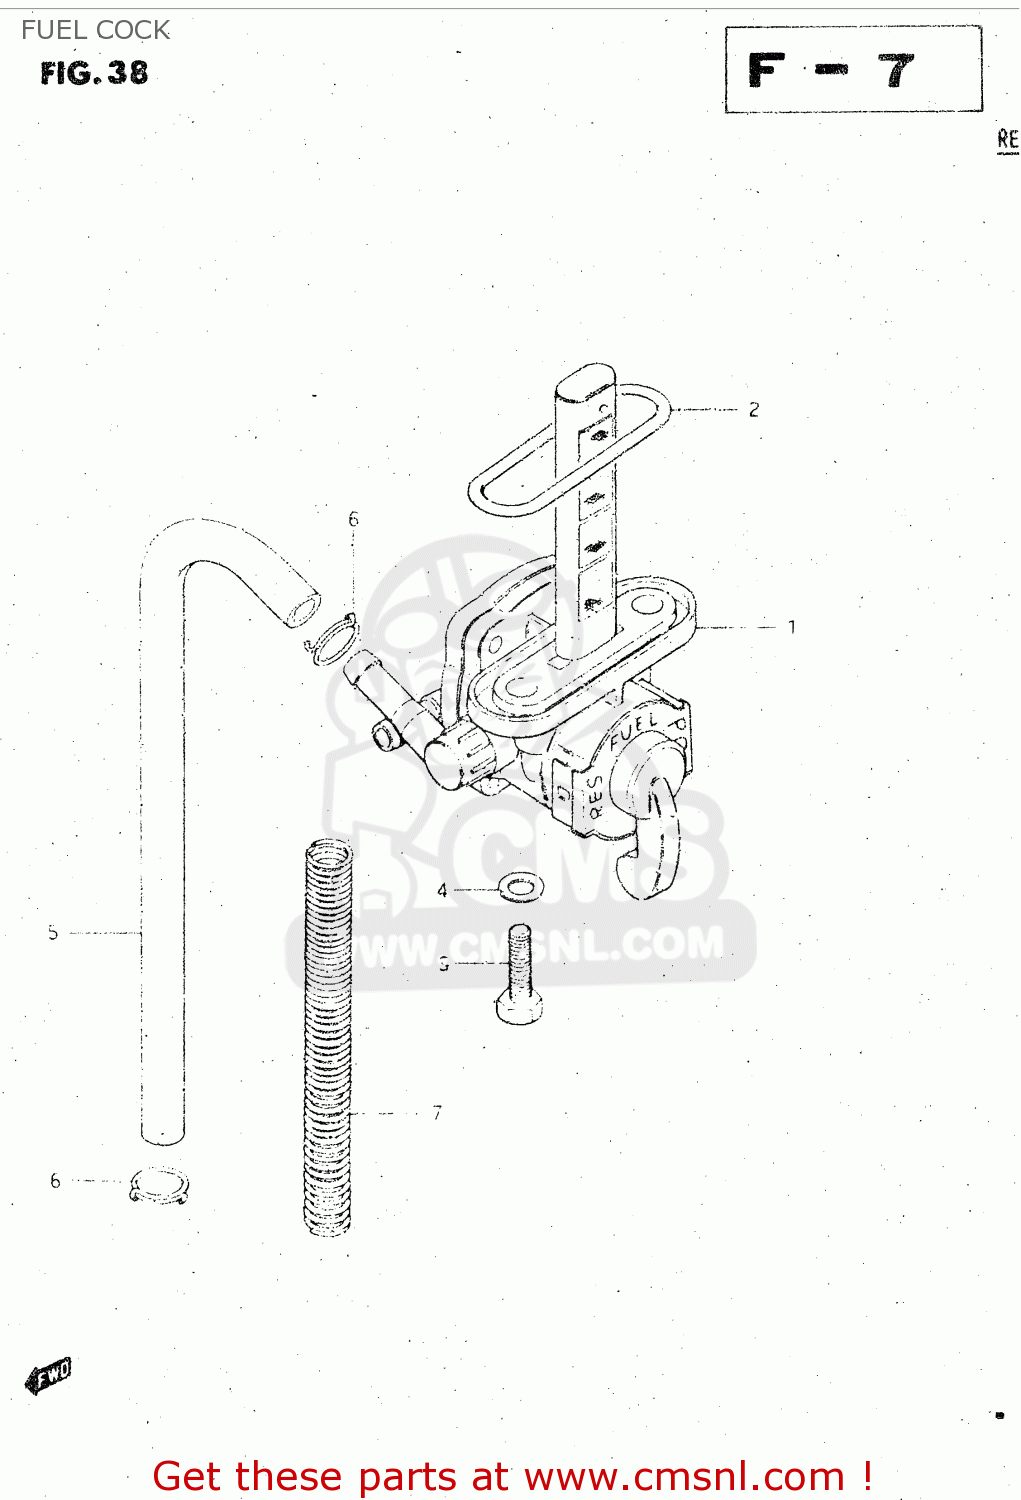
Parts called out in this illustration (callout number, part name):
1	COCK ASSEMBLY,FUEL
2	O RING
3	BOLT(6X20)
4	GASKET
5	HOSE
6	CLIP
7	SPRING
